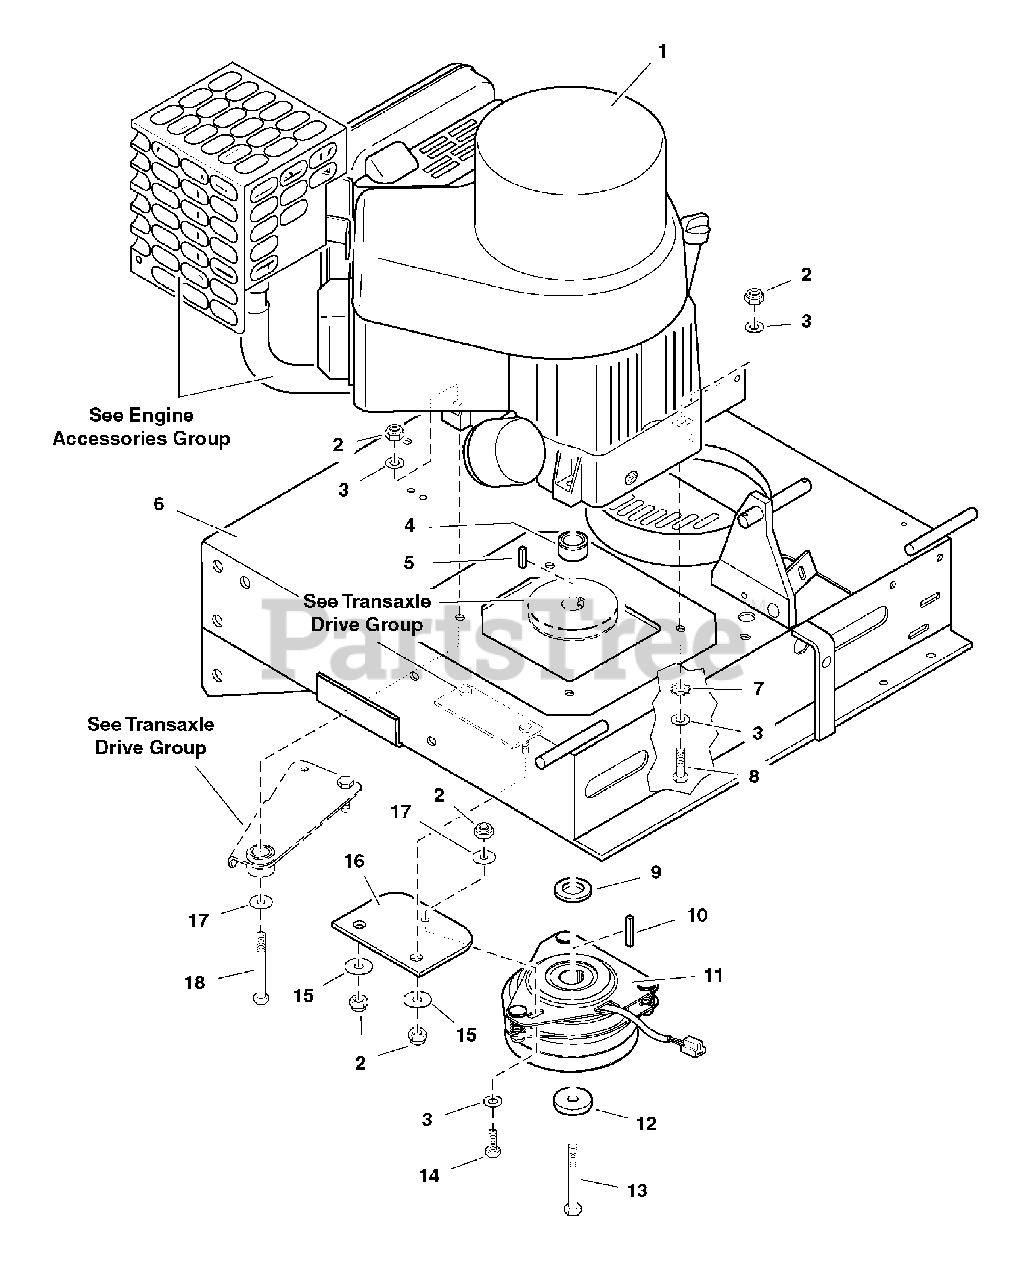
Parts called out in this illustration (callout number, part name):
1	ENGINE, 20HP Briggs & Stratton, Model #351777
2	NUT, Hex, Nylon Lock, 5/16-18
3	WASHER, 5/16
4	CRANKSHAFT SPACER
5	KEY, 1/4 Sq. x 5/8
6	ENGINE DECK
7	WASHER, Star, 5/16
8	CAPSCREW, Hex Hd, 5/16-18 x 1-1/4
9	CLUTCH SPACER
10	KEY, 1/4 Sq. x 1
11	ELECTRIC CLUTCH, PTO
12	WASHER, Retaining
13	CRANKSHAFT BOLT, 7/16 x 3
14	CAPSCREW, Hex Hd, 5/16-18 x 3/4
15	WASHER, Clutch Anchor
16	CLUTCH ANCHOR PAD
17	WASHER, Fender, 5/16
18	CAPSCREW, Hex Hd, 5/16-18 x 3
